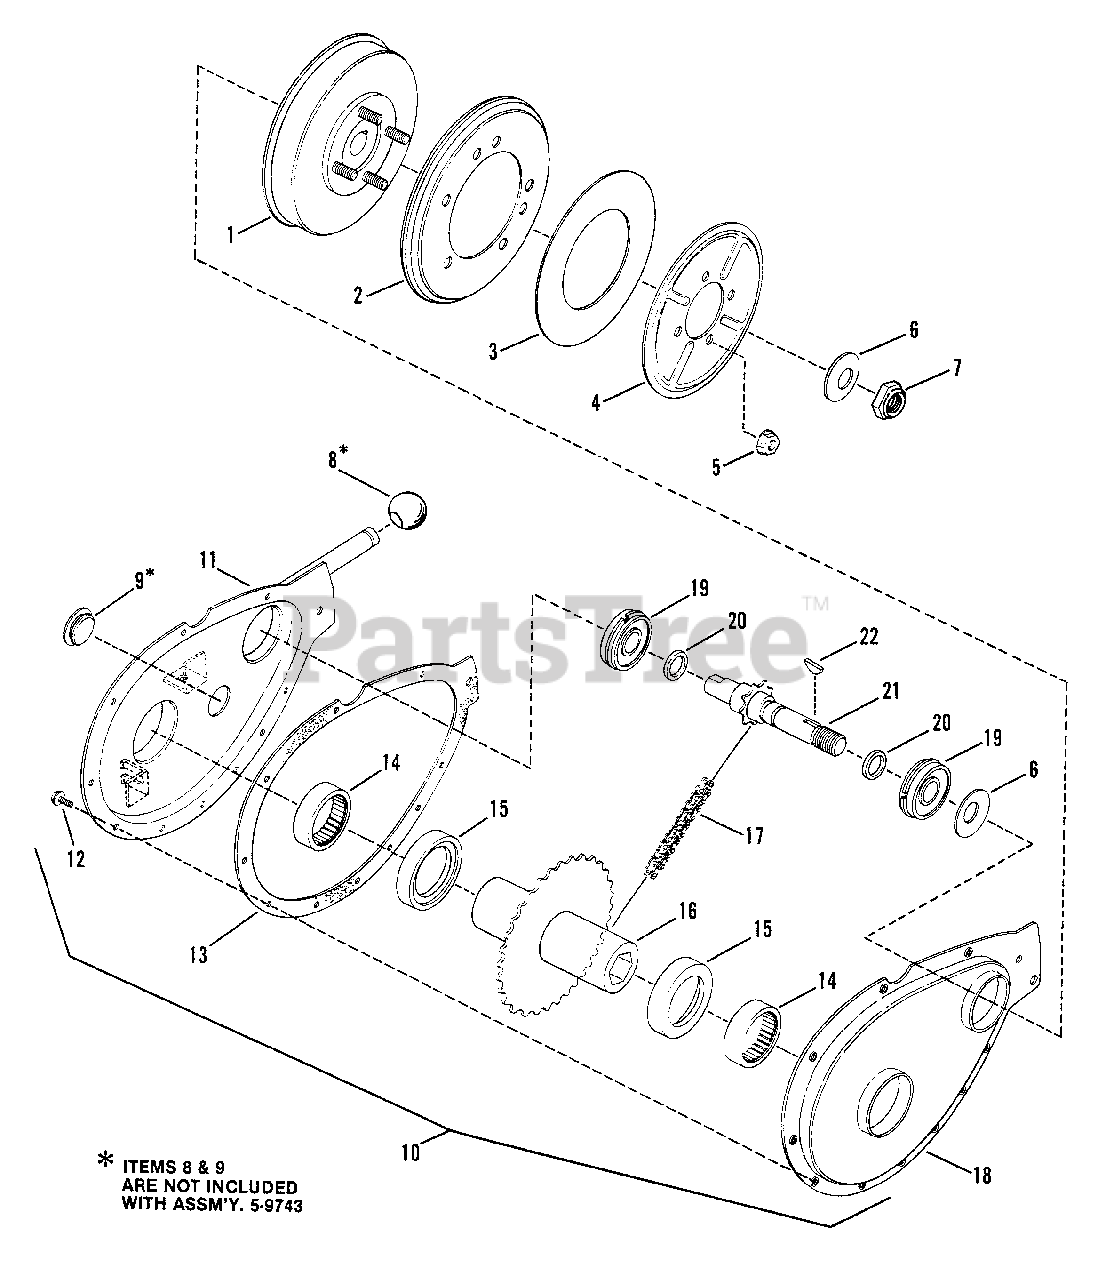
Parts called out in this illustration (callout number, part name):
1	HUB, Driven Disc
2	DISC, Driven
3	WASHER, Thrust
4	PLATE
5	NUT, 5/16-18 Hex Flange Lock
6	WASHER, Belleville
7	NUT, 5/8-18 Hex Lock
8	BUSHING, Primary Clutch Ball
9	PLUG, Oil Fill & Check
10	ASSEMBLY, Chain Case
11	CASE, Sprocket
12	SCREW, #10-24 x 1/2" Hex Washer Self-Tap (Torx)
13	GASKET, Case Cover
14	BEARING, Needle
15	WASHER, Nylon Thrust
16	HUB & SPROCKET
17	CHAIN
18	COVER, Chain Case
19	BEARING, Ball
20	"O"-RING
21	SPROCKET & SHAFT
22	KEY, Woodruff
